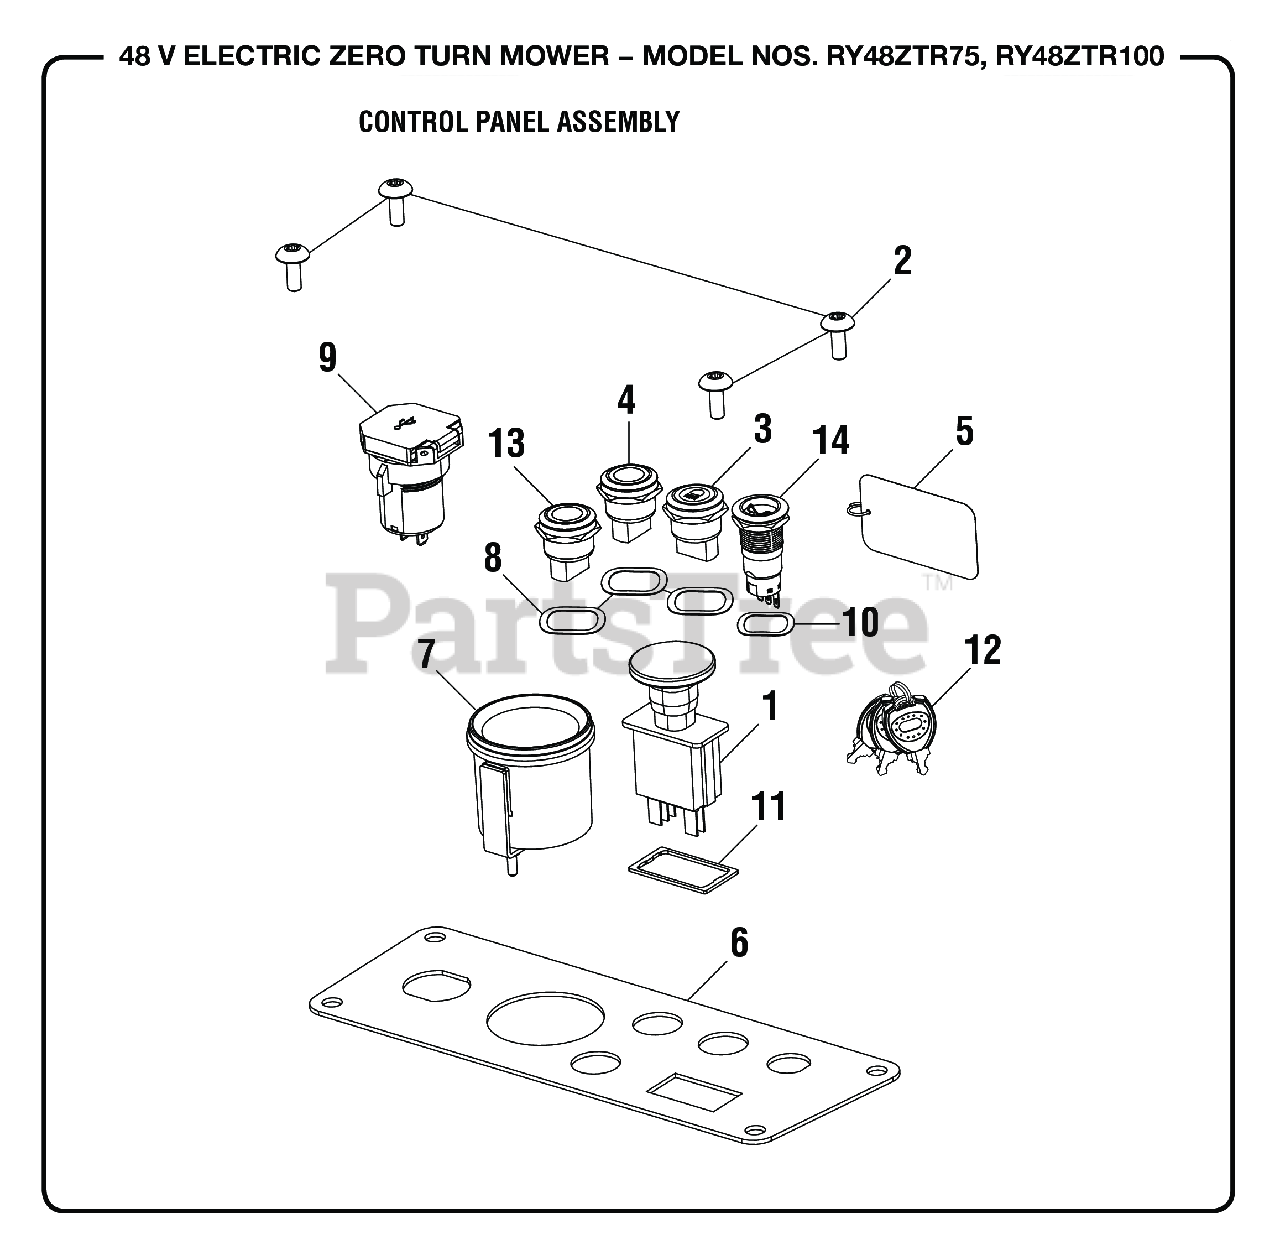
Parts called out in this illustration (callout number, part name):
1	Power Take Off Button (PTO)
2	Screw (M6 x 10 mm, Soc. Button Hd.)
3	Light Switch
4	Button Switch, Drive Speed
5	Watch For Kids, Keychain Label
6	Control Panel Face Plate
7	Fuel Gauge, ZTR
8	Wavy Washer
9	USB Module
10	Wavy Washer
11	PTO Gasket
13	Button Switch, Blade Speed
14	Switch Key Module
